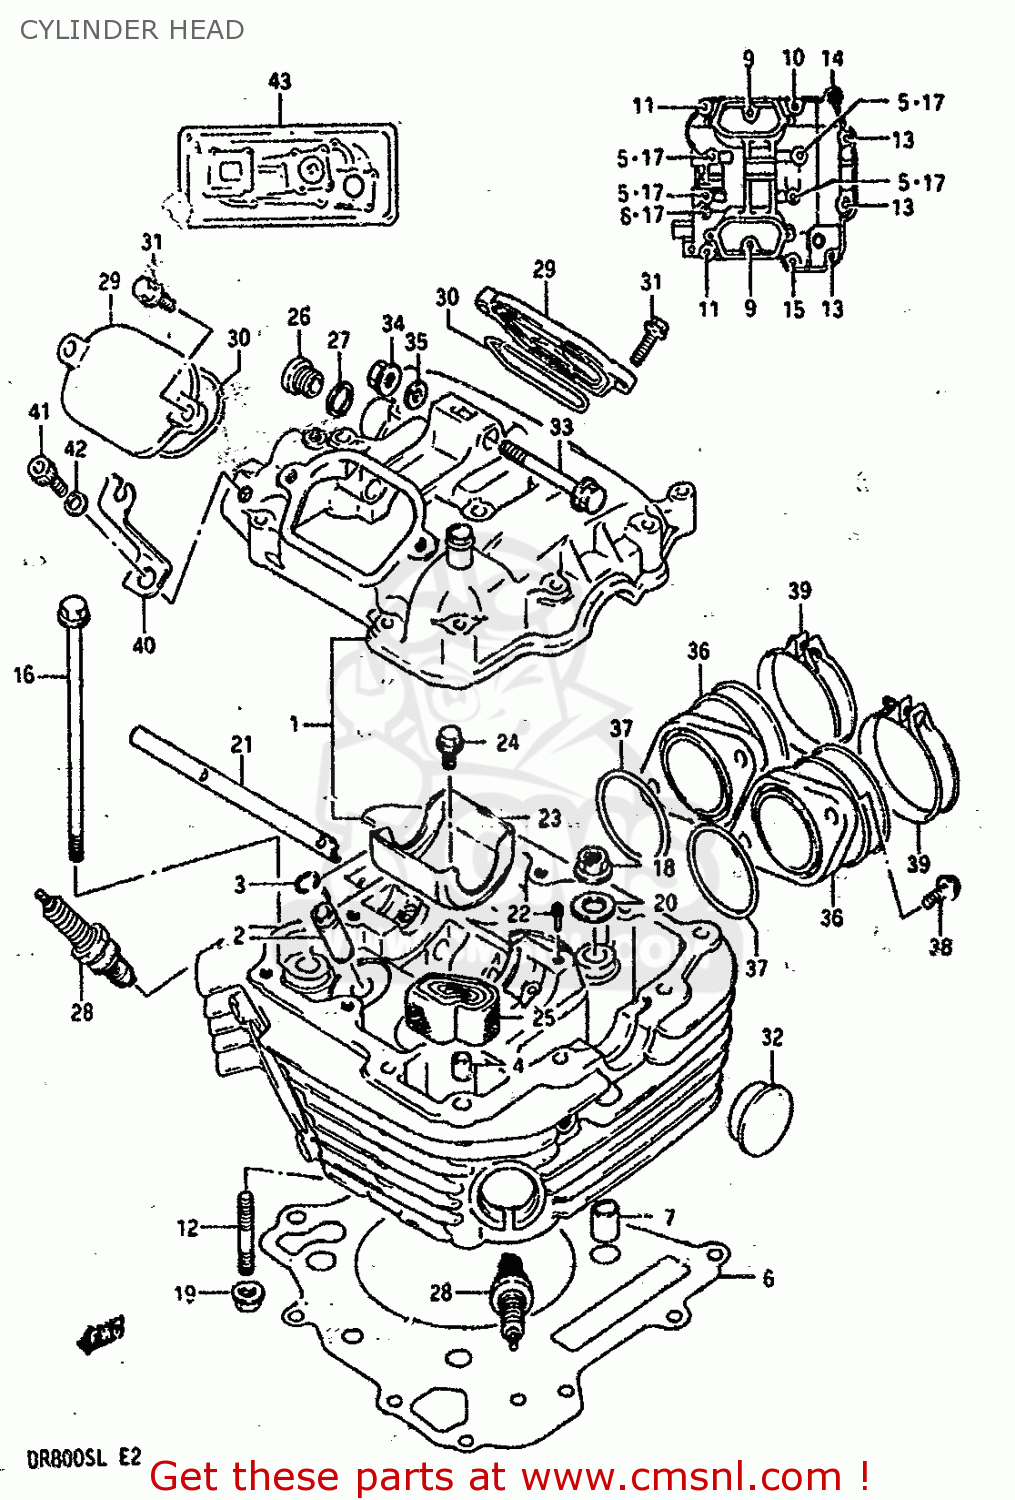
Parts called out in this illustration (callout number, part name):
1	HEAD ASSY,CYLINDER (GRAY)
2	GUIDE,VALVE
3	RING,SNAP
4	PIN(6.2X8X11)
5	BOLT(6X55)
6	GASKET,CYLINDER HEAD (NAS)
7	PIN
8	BOLT 6X16
9	BOLT
10	BOLT
11	BOLT 6X35
12	BOLT,STUD(8X31)
13	BOLT(6X125)
14	BOLT(6X115)
15	BOLT(6X105)
16	BOLT(8X155)
17	GASKET(5.8X13X1.2) (NAS)
18	NUT
19	NUT 8MM
20	WASHER(10.5X22X2.3)
21	PIPE,OIL
22	SCREW (L:19.5)
23	PLATE, OIL CHAMBER
24	BOLT
25	SEPARATOR,OIL
26	PLUG,14X12
27	GASKET(14X19.2X2) (NAS)
28	PLUG,SPARK(DPR9EA-9)
29	CAP,INSPECTION
30	O-RING,INSPECTION CAP
31	BOLT 6X20
32	PLUG(OD:30)
33	BOLT,ENGINE MOUNTING (L:55)
34	NUT
35	LOCK WASHER
36	PIPECOMP,INT
37	O RING(D:2.4,ID:39.7)
38	SCREW
39	CLAMP
40	HOLDER,DECOMP CABLE
41	BOLT
42	WASHER
43	GASKET SET
